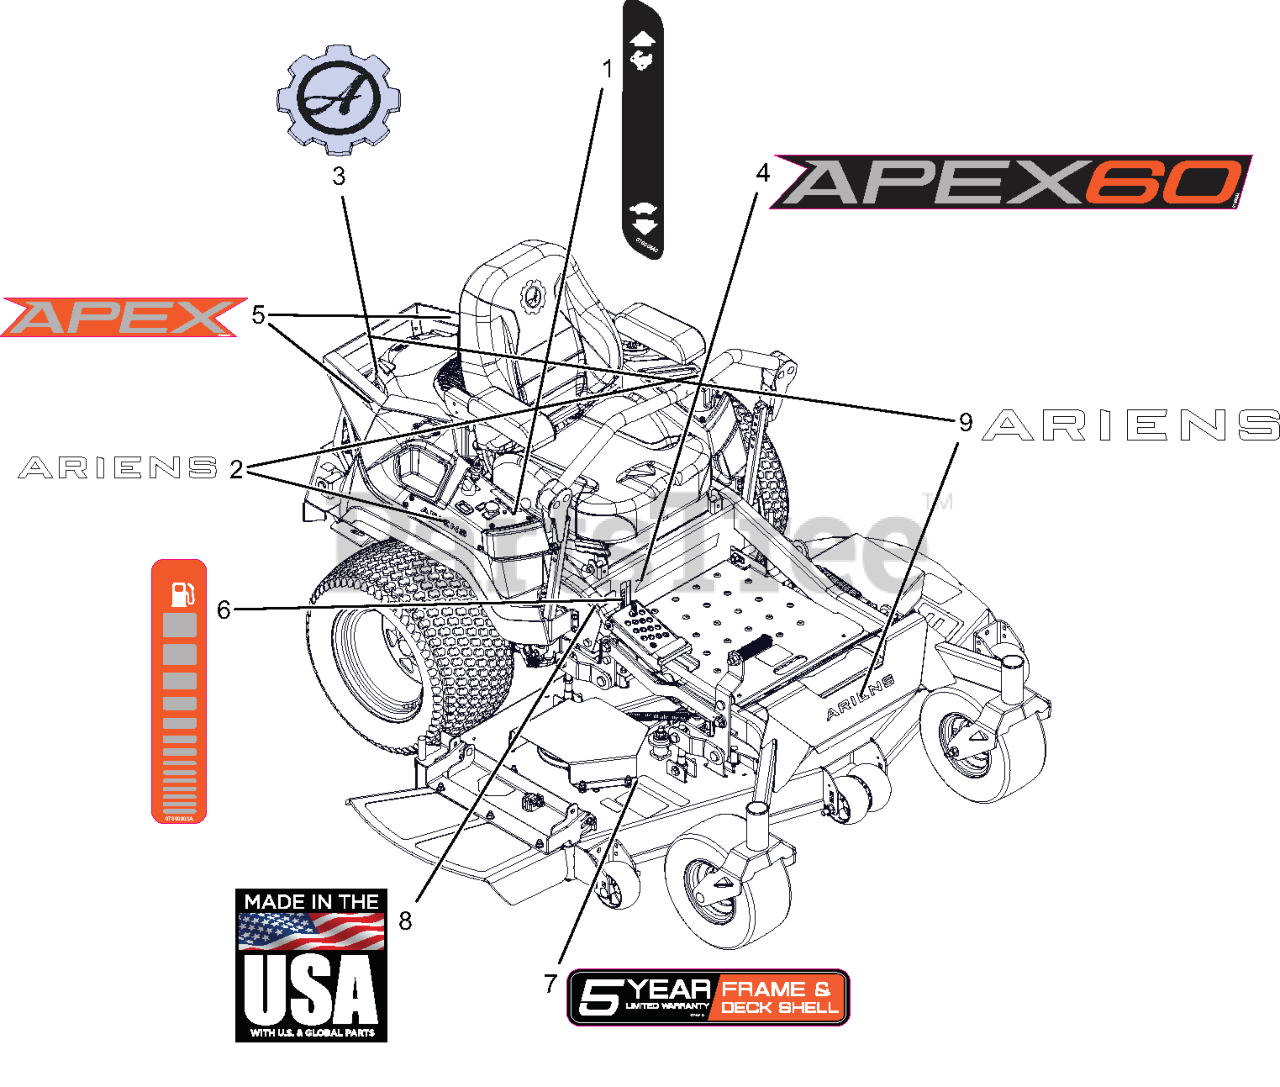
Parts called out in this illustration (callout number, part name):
1	DECAL, DASH
2	DECAL, ARIENS 6.00"
3	DECAL, ARIENS - GEAR BADGE (THK)
4	DECAL, KICKPLATE - ARIENS APEX 60
5	DECAL, APEX FENDER
6	DECAL, FUEL LEVEL - ARIENS APEX
7	DECAL, DECK - 5 YEAR ARIENS
8	DECAL, MADE IN USA
9	DECAL, ARIENS - BADGE
